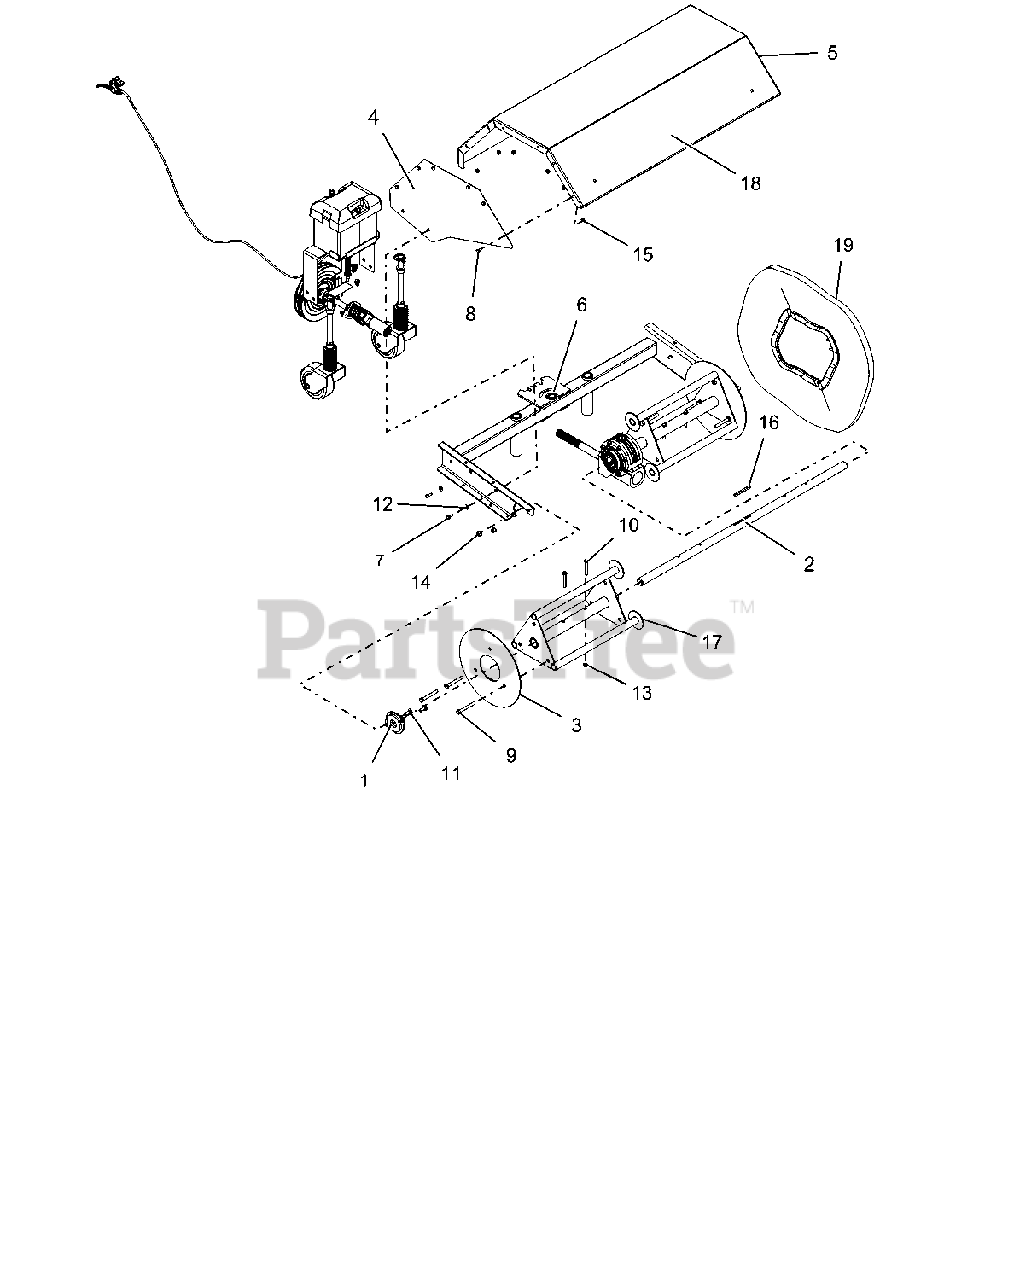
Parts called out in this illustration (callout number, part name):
1	BEARING,2 BOLT FLANGE 1-1/8 ID
2	CENTER, SHAFT
3	PLATE, END RETAINER
4	WLDT, SIDE COVER - RH
5	WLDT, SIDE COVER - LH
6	FRAME, POWER BROOM 36"
7	BLT-HEX .25-20X.75 GR5 YWZC
8	BLT-HEX .25-20X.50 GR5 YWZC
9	BLT-HEX .38-16X3.00 GR5 FTH YZ
10	BLT-HEX .31-18X2.25 GR5 YWZC
11	BLT-RDHDSQNK .38-16X1.00 G5YZ
12	WSHR-FL-STL.312X.734X.065 YWZ
13	NUT-LK-CTR .31-18 YWZC
14	NUT-LK-TOP-FLG .38-16 YWZC
15	NUT-LK-TOP-FLG .25-20 YWZC
16	KEY .25 X .25 X 3IN
17	PB36 DRIVE CORE SERVICE KIT
18	COVER,TOP-36" BRUSH W/DECALS
19	KIT, BRISTLE - SET OF 18
